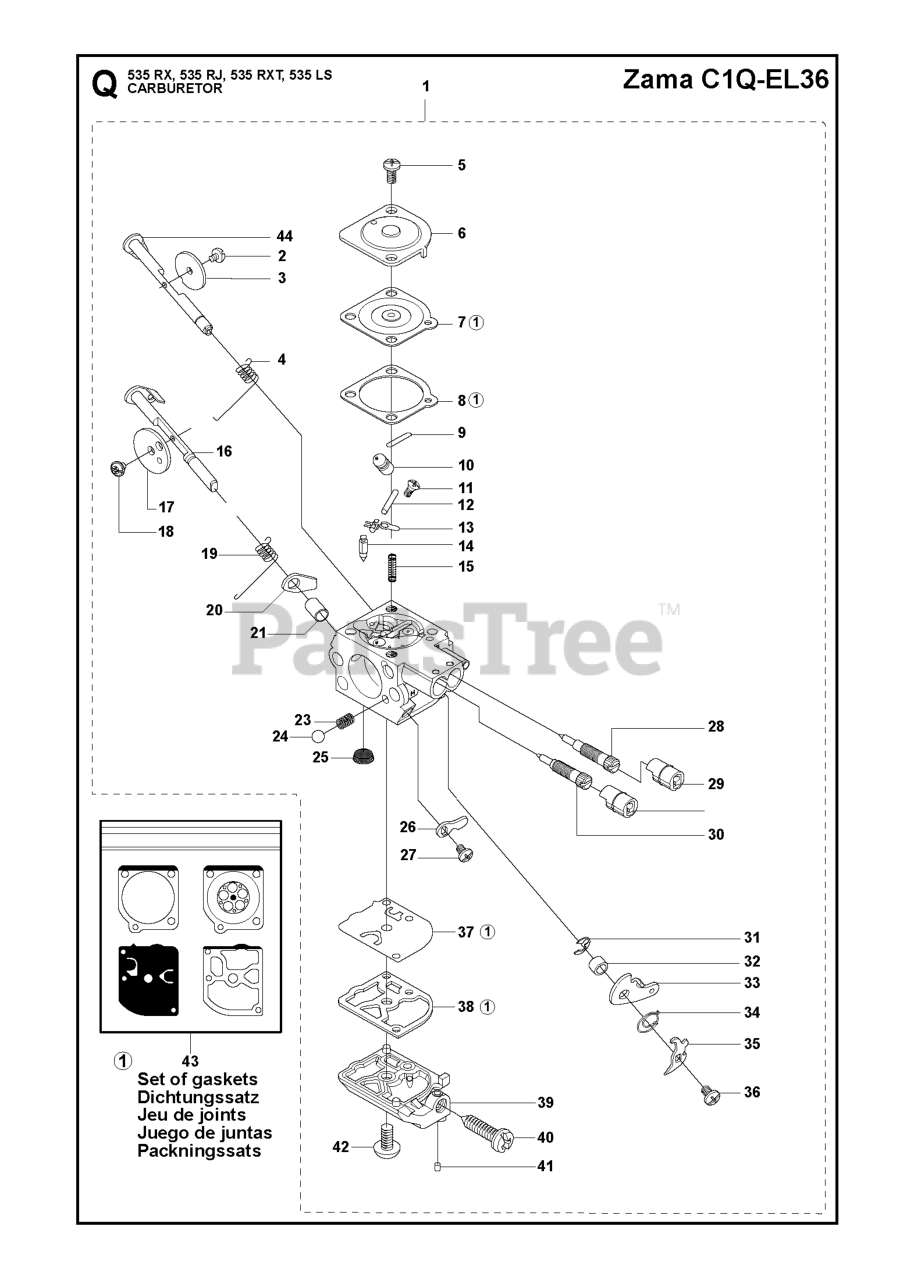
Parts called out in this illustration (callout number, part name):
1	CARBURETOR C1QEL36
4	RETURN SPRING
12	PIN RETAINING SCREW
14	INLET NEEDLE
15	SPRING
16	CHOKE SHAFT
17	DISC
25	FUEL INLET SCREEN
28	IDLE SCREW
29	LIMITER CAP KIT
34	SPRING
37	PUMP DIAPHRAGM
43	GASKET KIT (ZAMA GND39)
44	THROTTLE SHAFT
